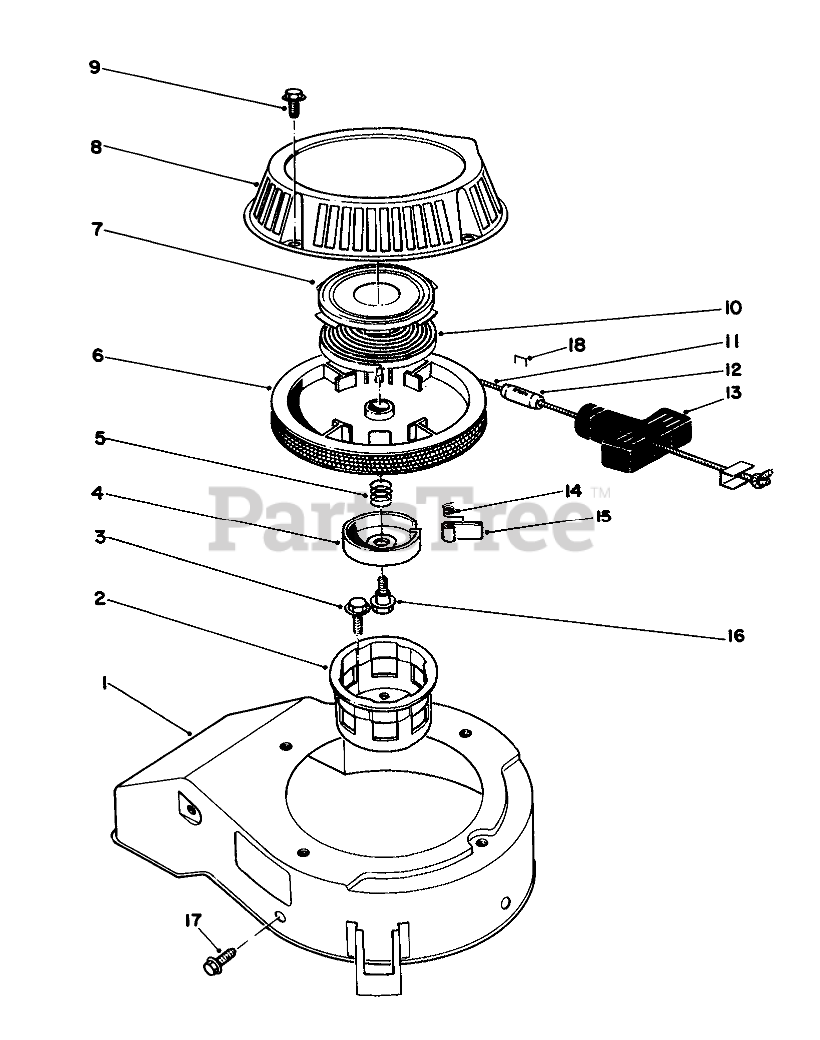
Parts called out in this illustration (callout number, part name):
1	COVER
2	CUP - STARTER
4	RETAINER
5	SPRING
7	Retainer Cup-Recoil Spring
9	SCREW-HHF
10	Spring-Recoil
11	ROPE-STARTER
12	STOP-ROPE
13	HANDLE-RECOIL
14	SPRING
18	Staple
